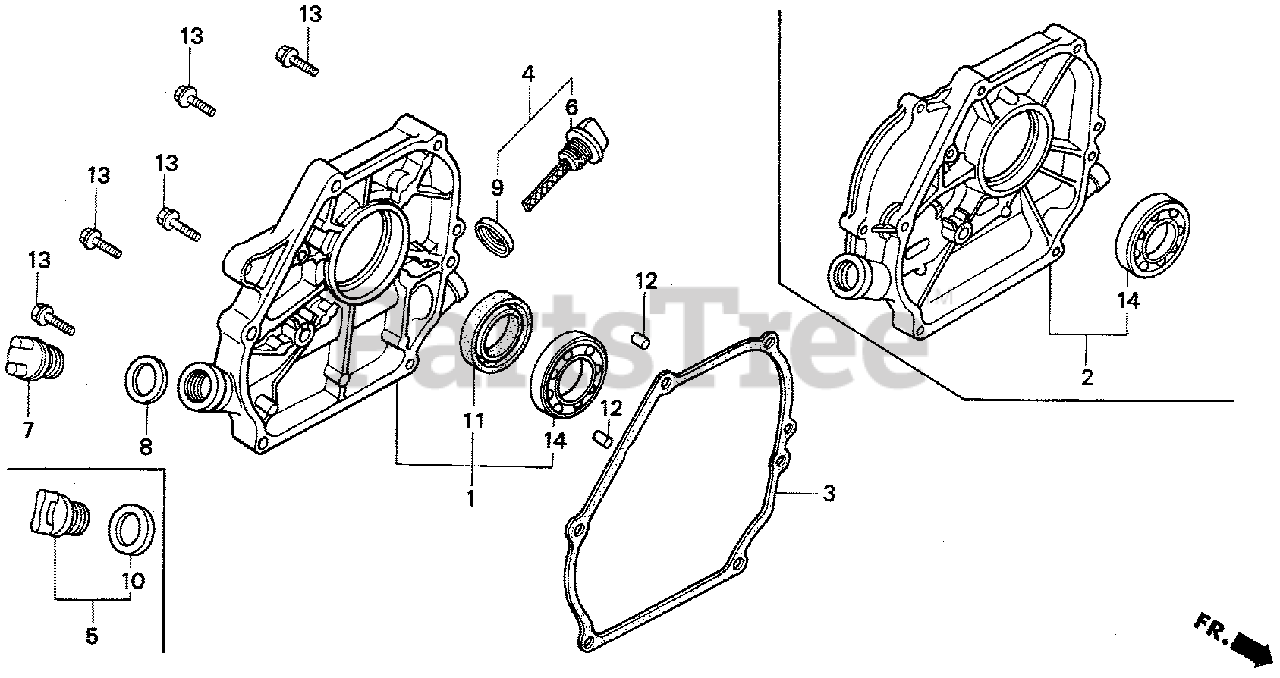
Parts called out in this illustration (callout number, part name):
2	COVER ASSY., CRANKCASE (L-TYPE)
3	GASKET, CASE COVER
3	GASKET, CASE COVER (NON-ASBESTOS)
4	CAP ASSY., OIL FILLER
5	CAP ASSY., OIL FILLER
6	CAP, OIL FILLER
7	CAP, OIL FILLER
8	GASKET, OIL FILLER CAP
9	GASKET, OIL FILLER CAP
10	GASKET, OIL FILLER CAP
12	PIN A, DOWEL (8X14)
13	BOLT, FLANGE (8X32)
14	BEARING, RADIAL BALL (6205)
